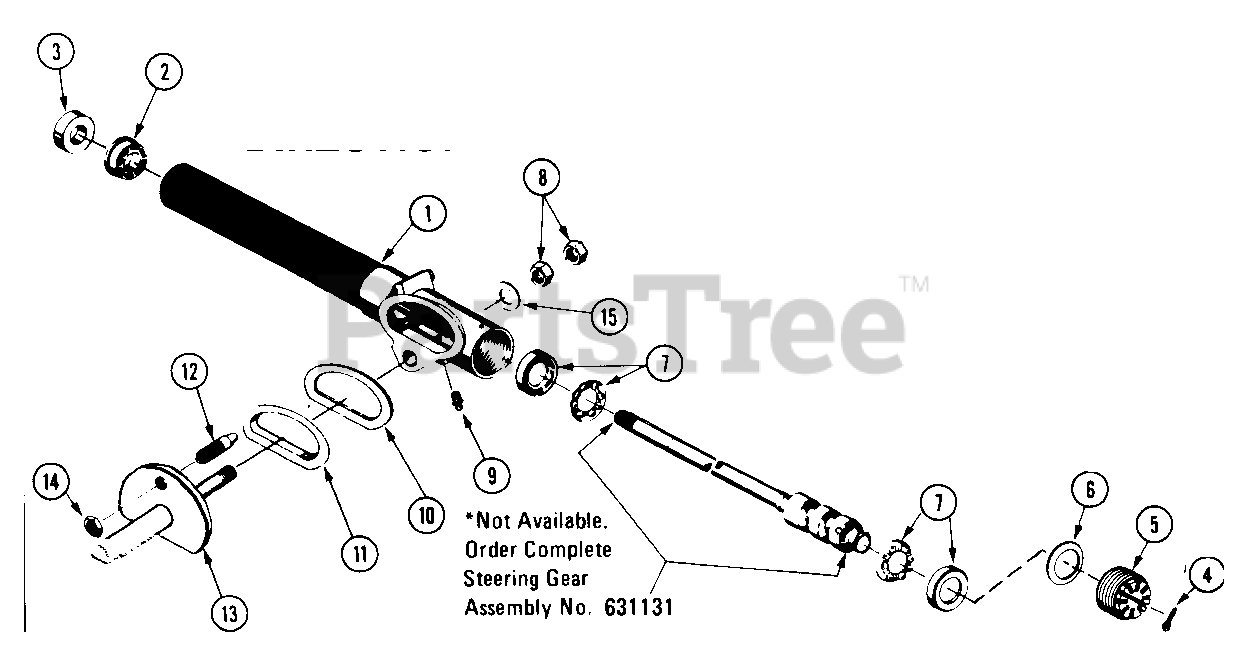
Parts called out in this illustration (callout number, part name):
1	HOUSING ASSEMBLY
2	BSHG ROSS G#061013
3	DUST COVER
4	PIN-COTR .12X.50 PL
5	PLUG-ADJUSTING
6	WSHR-BLVL 1.015X1.470X.044
7	BEARING KIT
8	NUT-JAM .75-16 PL
9	HYDRAULIC DRIVE FITTING
11	RETAINER - SEAL
12	STEERING SHAFT
12	LEVER
13	STEERING GEAR SHAFT
14	NUT-JAM .562-18
15	WSHR-FL-STL .760X1.250X.060 PL
